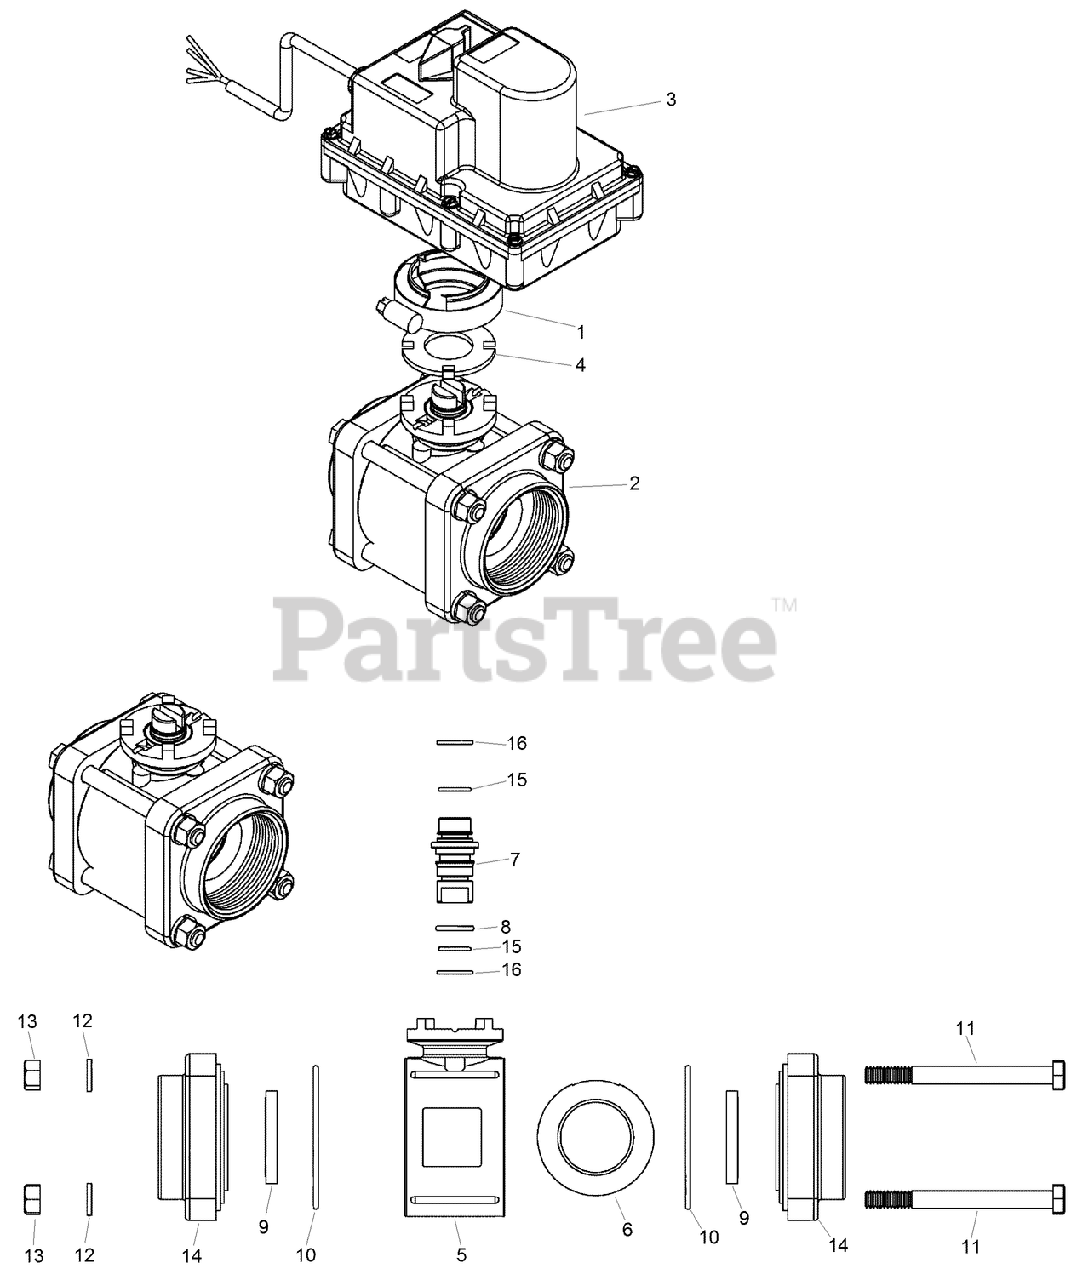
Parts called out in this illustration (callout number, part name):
1	CLAMP-FLANGE
4	FILTER
5	BODY-VALVE
6	BALL-HOLLOW
7	STEM-VALVE
8	O-RING
9	SEAT-VALVE
10	O-RING
14	PLATE-END
15	O-RING
16	SEAL-VALVE
